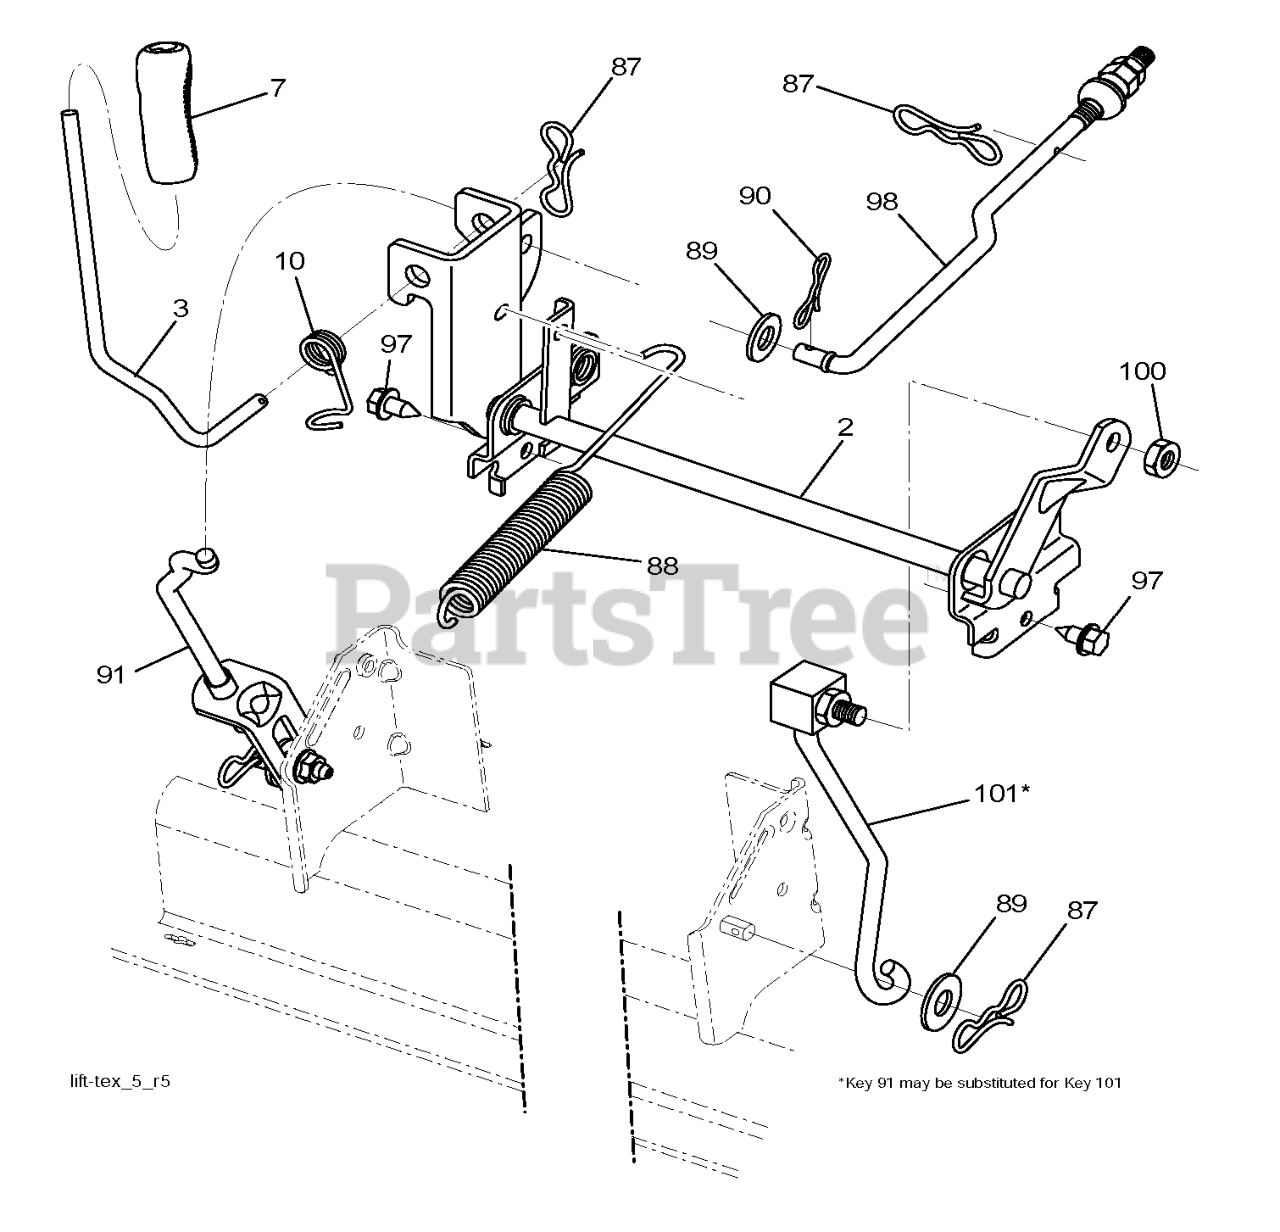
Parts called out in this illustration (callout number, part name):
2	SHAFT.ASM.LIFT.CROSS.H
3	LEVER.LIFT.HANDLE.LT
7	GRIP.HANDLE.LIFT.PVC.BLACK
10	SPRING.TORSION.LIFT.HANDLE
87	PIN.COTTER.7/16.BOW TI.
88	SPRING.LIFT.ASSIST
89	WASHER.CLEAR.ZINC
90	PIN.COTTER.5/16.BOW TI
91	LINK.ASM.LIFT.REAR
97	SCREW, 3/8-16X3/4
98	LINK.ASM.SUSP.FRONT.MW
100	LOCKNUT
101	LINK.ASM.LIFT.FIXE.38/42/46"
